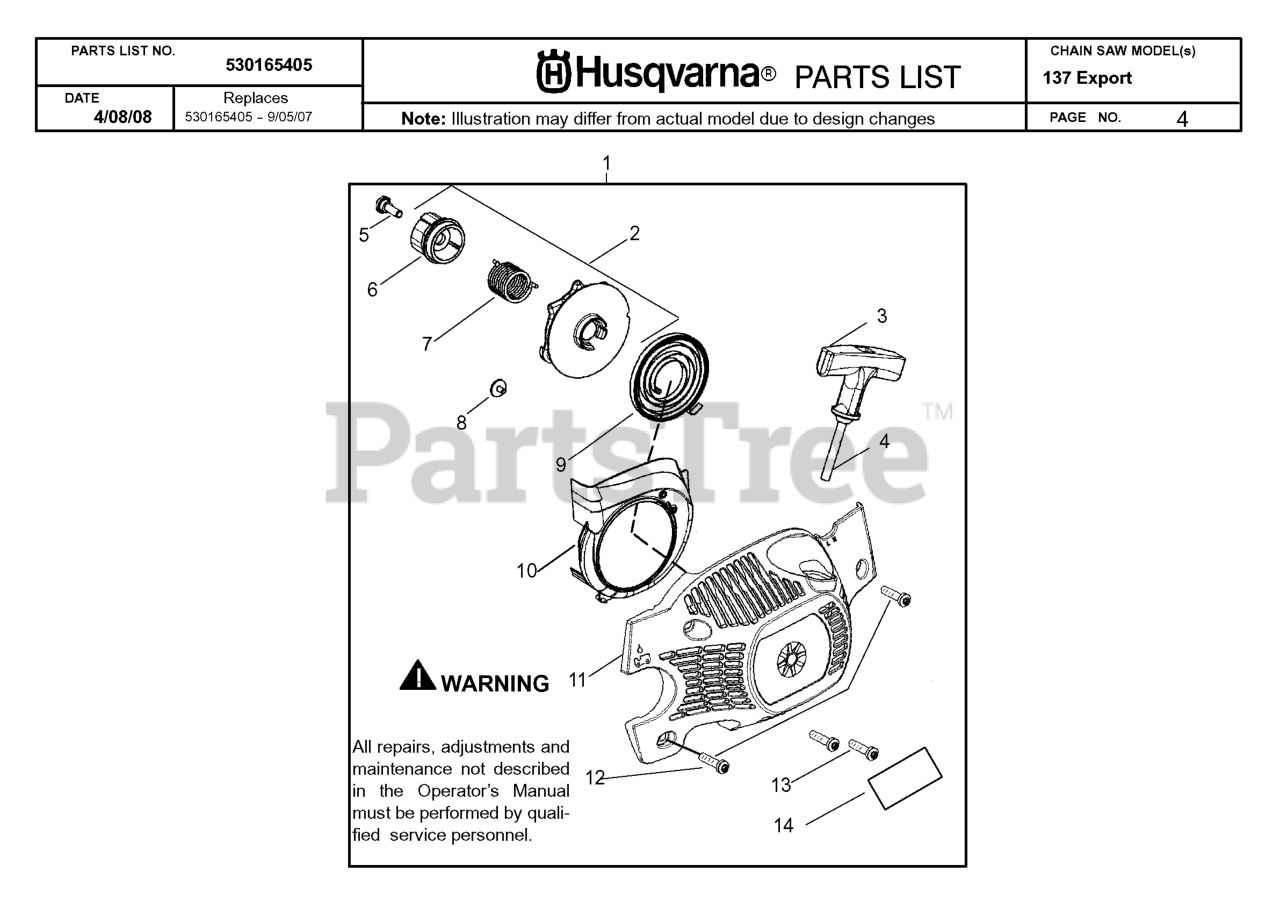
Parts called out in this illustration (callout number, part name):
1	KIT FAN HSG & STARTER EPS
2	KIT EPS STARTER
3	STARTER HANDLE GRAY
5	SCREW SHOULDER
6	HUB STARTER EPS
7	SPRING EPS
9	SPRING STARTER
10	BAFFLE AIR
11	HOUSING FAN W/ EYELET
13	SCREW,STRTR CVR 36/41
14	DECAL 137 STARTER
